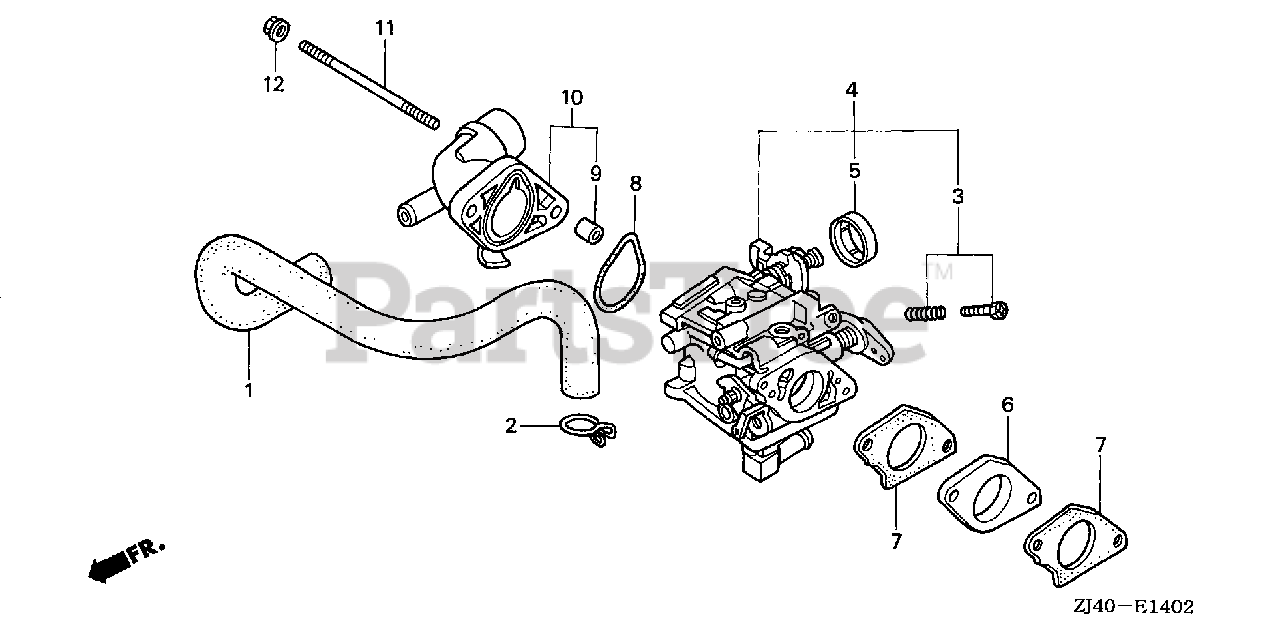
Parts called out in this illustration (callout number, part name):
1	TUBE, BREATHER
2	CLIP, BREATHER TUBE
4	CARBURETOR ASSY. (BGL3A A)
5	CAP, CHOKE DUST
6	INSULATOR, CARBURETOR
7	GASKET, CARBURETOR
8	GASKET, AIR CLEANER
9	COLLAR A, AIR CLEANER
10	ELBOW, AIR CLEANER
11	BOLT, STUD (6X108)
12	NUT, FLANGE (6MM)
